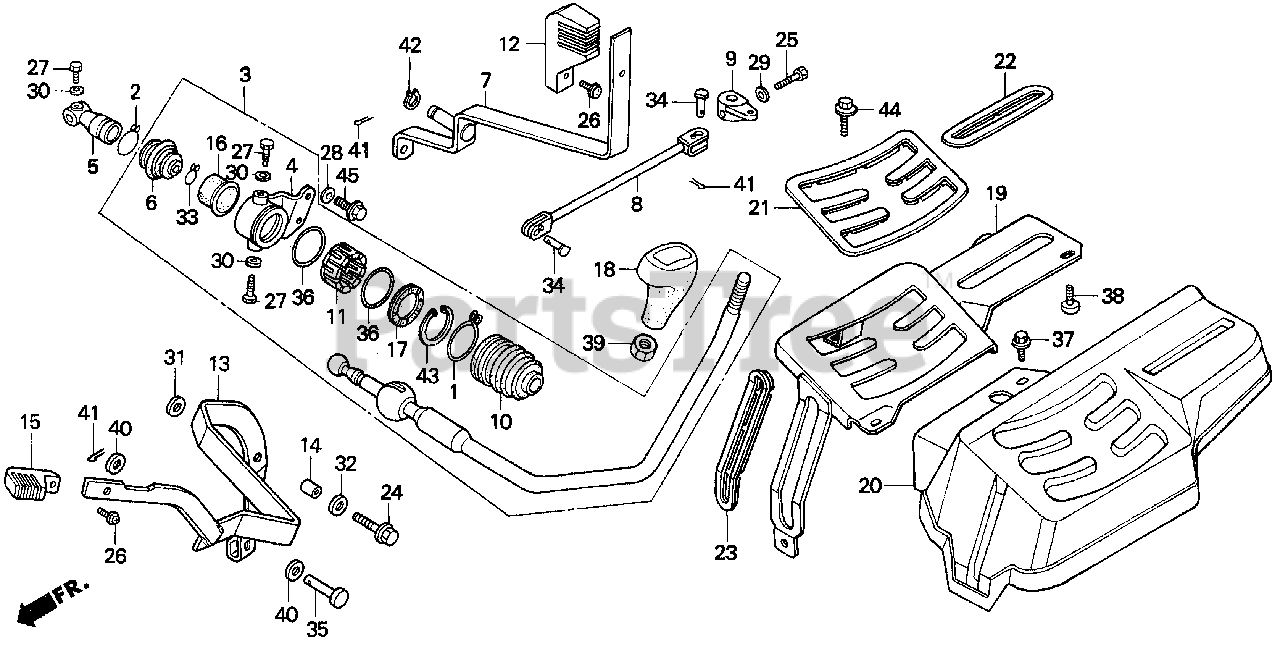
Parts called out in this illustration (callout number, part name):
1	CLIP, AIR IN. TUBE
2	CLIP, MUFFLER GASKET SETTING
3	LEVER ASSY., CHANGE
4	HOLDER, CHANGE LEVER
5	ARM, CHANGE LEVER
6	BOOT, CHANGE LEVER (A)
7	LEVER, P.T.O. SHIFT
8	ROD, P.T.O. CHANGE
9	ARM, P.T.O. CHANGE
10	BOOT, CHANGE LEVER (B)
11	SEAT, CHANGE LEVER BALL
12	KNOB C, P.T.O. LEVER *Y121* (YELLOW)
13	LEVER, AUXILIARY CHANGE
14	COLLAR (8X12X10.2)
15	KNOB B, CHANGE LEVER *YR161* (ORANGE)
16	DUST SEAL B, CHANGE
17	STOPPER, CHANGE LEVER BALL
18	KNOB, SHIFT LEVER
19	GUIDE, L. CONTROL
20	PANEL, L. CONTROL *R165* (JOLLY RED)
21	TRIM, LEVER GUIDE (B)
22	TRIM, LEVER GUIDE (A)
23	TRIM, SHIFT GUIDE
24	BOLT, FLANGE (8X35)
25	BOLT, HEX. (6X21)
26	SCREW, HINGE PATCH
27	BOLT, SPECIAL (8X24)
28	WASHER, PLAIN (10MM)
29	WASHER, CONICAL SPRING (6MM)
30	WASHER, CONICAL SPRING (8MM)
31	WASHER, PLAIN (8X24X6)
32	WASHER, PLAIN (8X23X3.2)
33	CLIP, AIR HOSE (16)
34	PIN, P.T.O. CHANGE ROD
35	PIN, FLAT (6X27.5)
36	O-RING (35X3)
37	BOLT-WASHER (6X16)
38	SCREW, TAPPING (6X12)
39	NUT, HEX. (12MM)
40	WASHER, PLAIN (6MM)
41	PIN, COTTER (1.6X25)
42	CIRCLIP (OUTER) (12MM)
43	CIRCLIP (INNER) (40MM)
44	BOLT, FLANGE (8X16)
45	BOLT, FLANGE (10X28)
